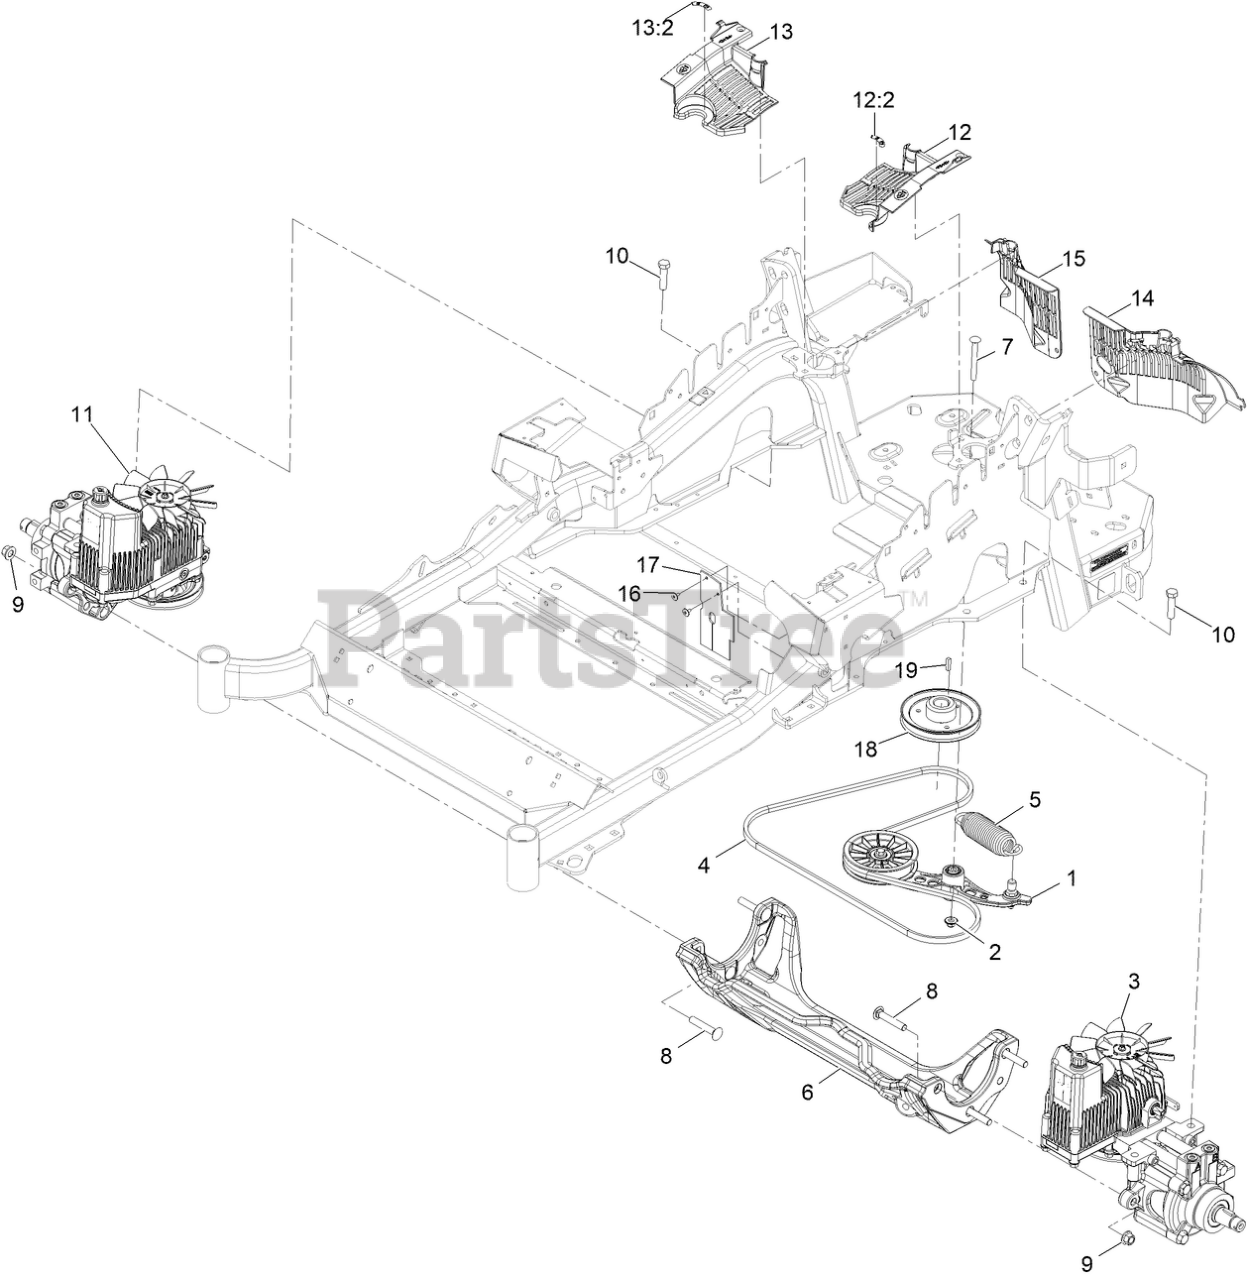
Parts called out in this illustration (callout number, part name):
1	PUMP IDLER ASM
2	Nut-Nyloc 3/8-16 Flg
3	HYDRO-LH
5	SPRING-EXTENSION
6	CRADLE-HYDRO
7	BOLT-SHOULDER, CARRIAGE 3/8-16 X 3 1/2
8	SCREW-CARR
9	Nut-Lock 1/2-13
10	SCREW-HH
11	HYDRO-RH
12	LH HYDRO GUARD ASM
12:2	DECAL-OIL, HYDRO
13	RH HYDRO GUARD ASM
13:2	DECAL-OIL, HYDRO
14	GUARD-HYDRO, REAR (LH)
15	GUARD-HYDRO, REAR (RH)
16	RIVET-POP
17	DEFLECTOR-AIR FLOW
18	SHEAVE, W/HUB
